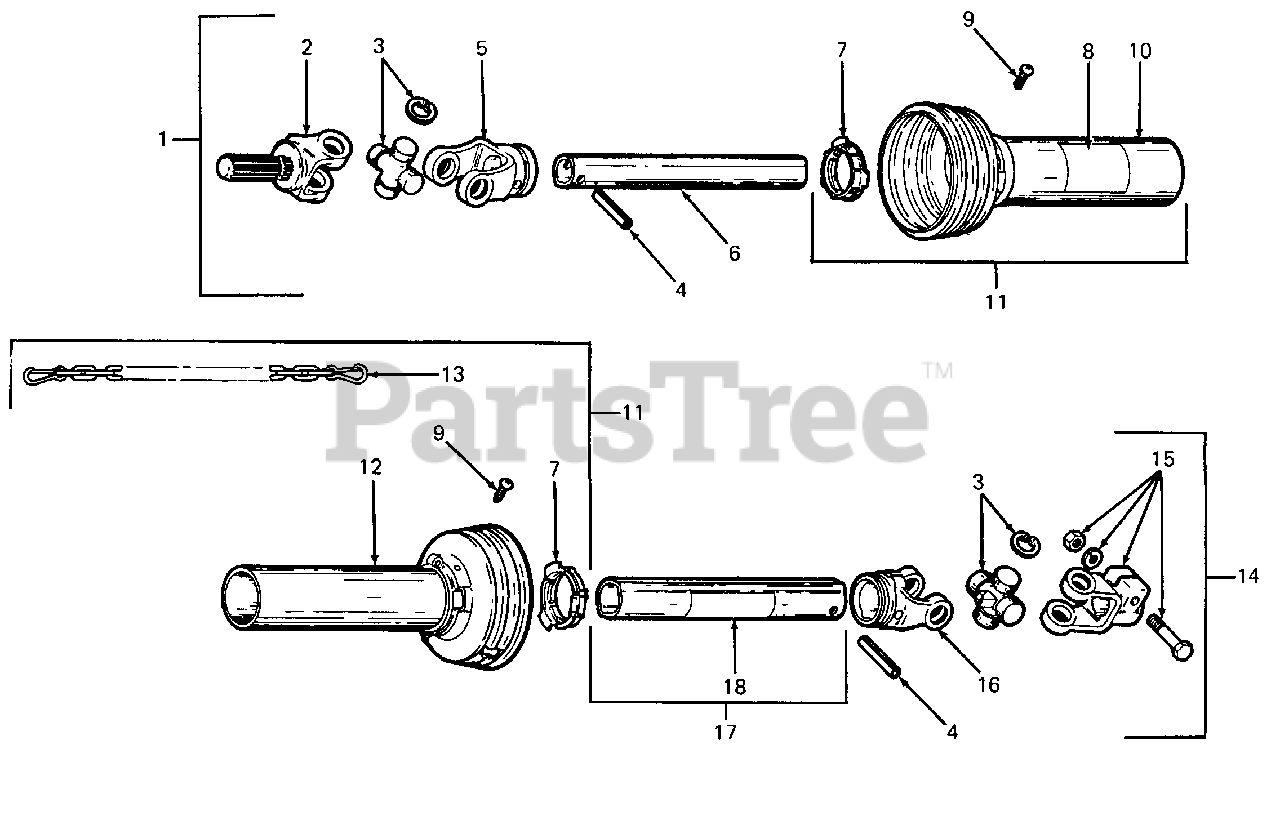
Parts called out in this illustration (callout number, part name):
1	Outer Half Assy, Shielded
2	Yoke, Spline, 1"-15
3	Bearing Kit, Cross
4	Pin, Spring
5	Yoke, Inboard
6	Inner Profile
7	Bearing Ring
10	Shield, Outer
11	Shield Kit (Includes Ref. No. 7 [Qty 2], 8, 9 [Qty 2], 10, 12 & 13)
12	Shield, Inner
13	Chain, Safety
14	Inner Half Assy, Shielded
16	Yoke, Inboard
17	Outer Profile w/Decal
